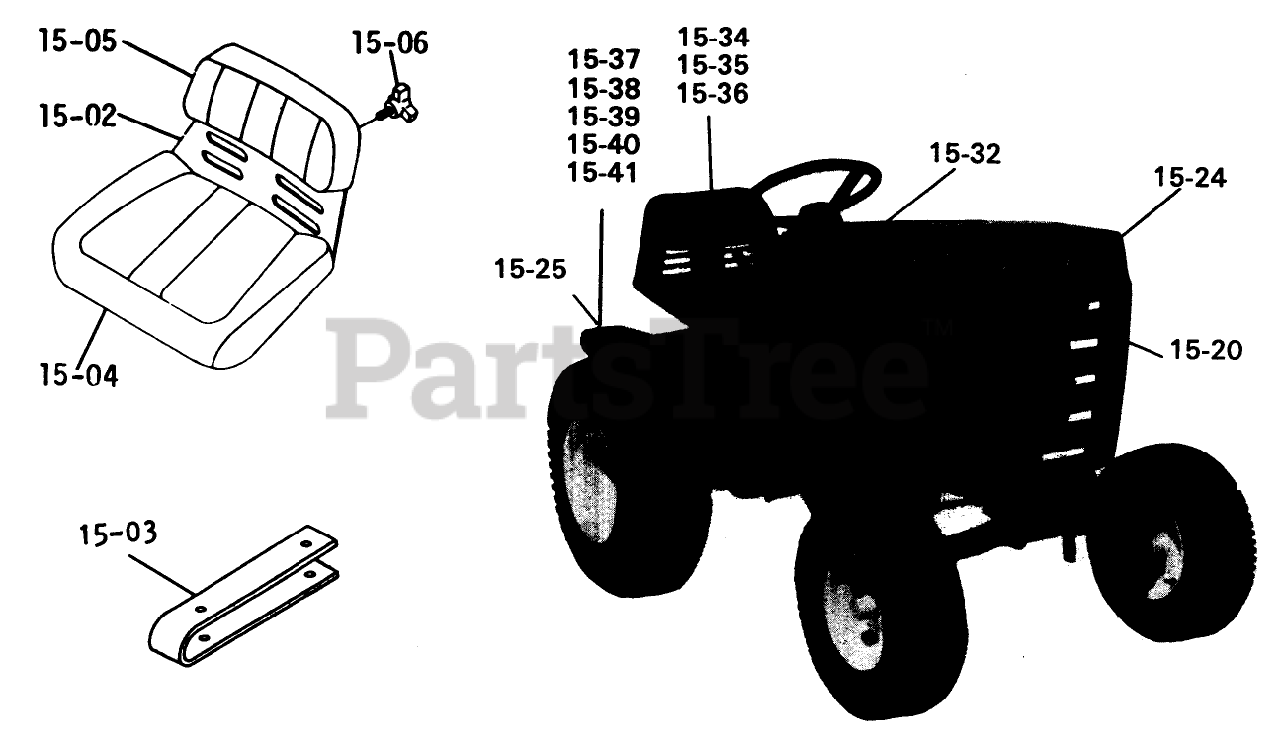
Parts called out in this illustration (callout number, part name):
15-05	BULLT 281
15-34	Washer
15-35	Decal-Read Manual
15-36	DECAL-HAND LIFT
